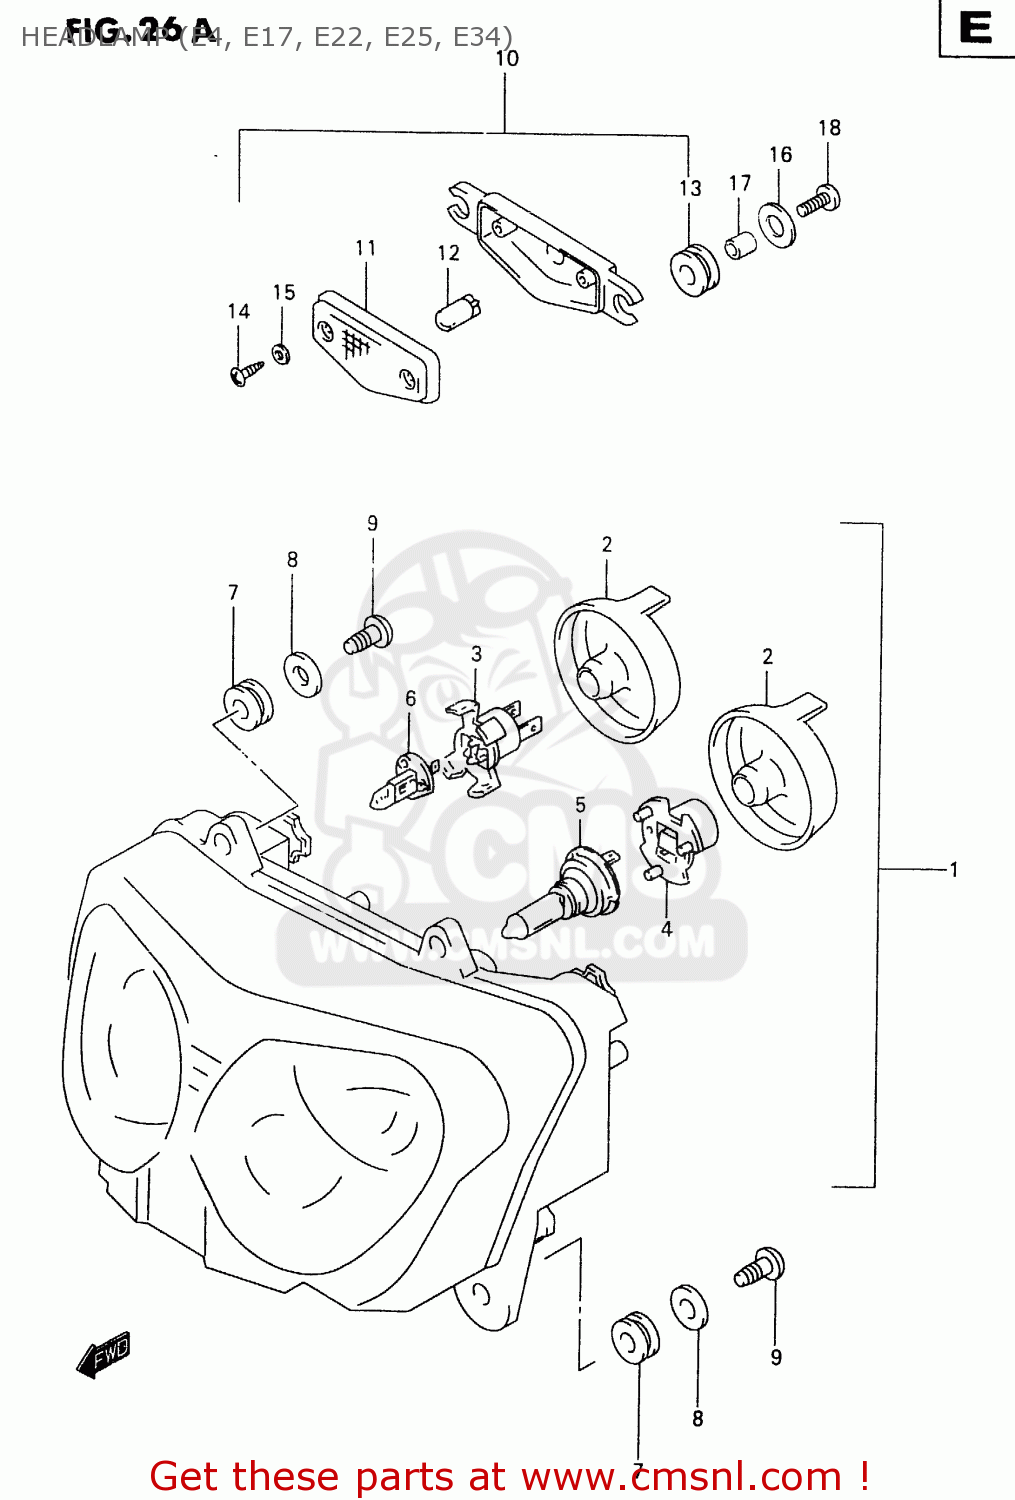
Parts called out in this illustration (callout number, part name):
1	HEADLAMP ASSY
2	COVER,SOCKET
3	ADAPTER ASSY
4	ADAPTER ASSY
5	BULB(12V55W/H7/PX26D/PHILIPS)
6	BULB(12V55W/H1/P14.5S/OSRA,PHI
7	CUSHION,HEADLAMP
8	WASHER(5.5X18X1)
9	SCREW,SIDE HOL
10	LAMP ASSY,FR POSITION
11	LENS
12	BULB(12V5W)
13	CUSHION
14	SCREW
15	WASHER
16	WASHER(5.5X18X1)
17	SPACER(5.5X8X10.5)
18	SCREW 5X20
